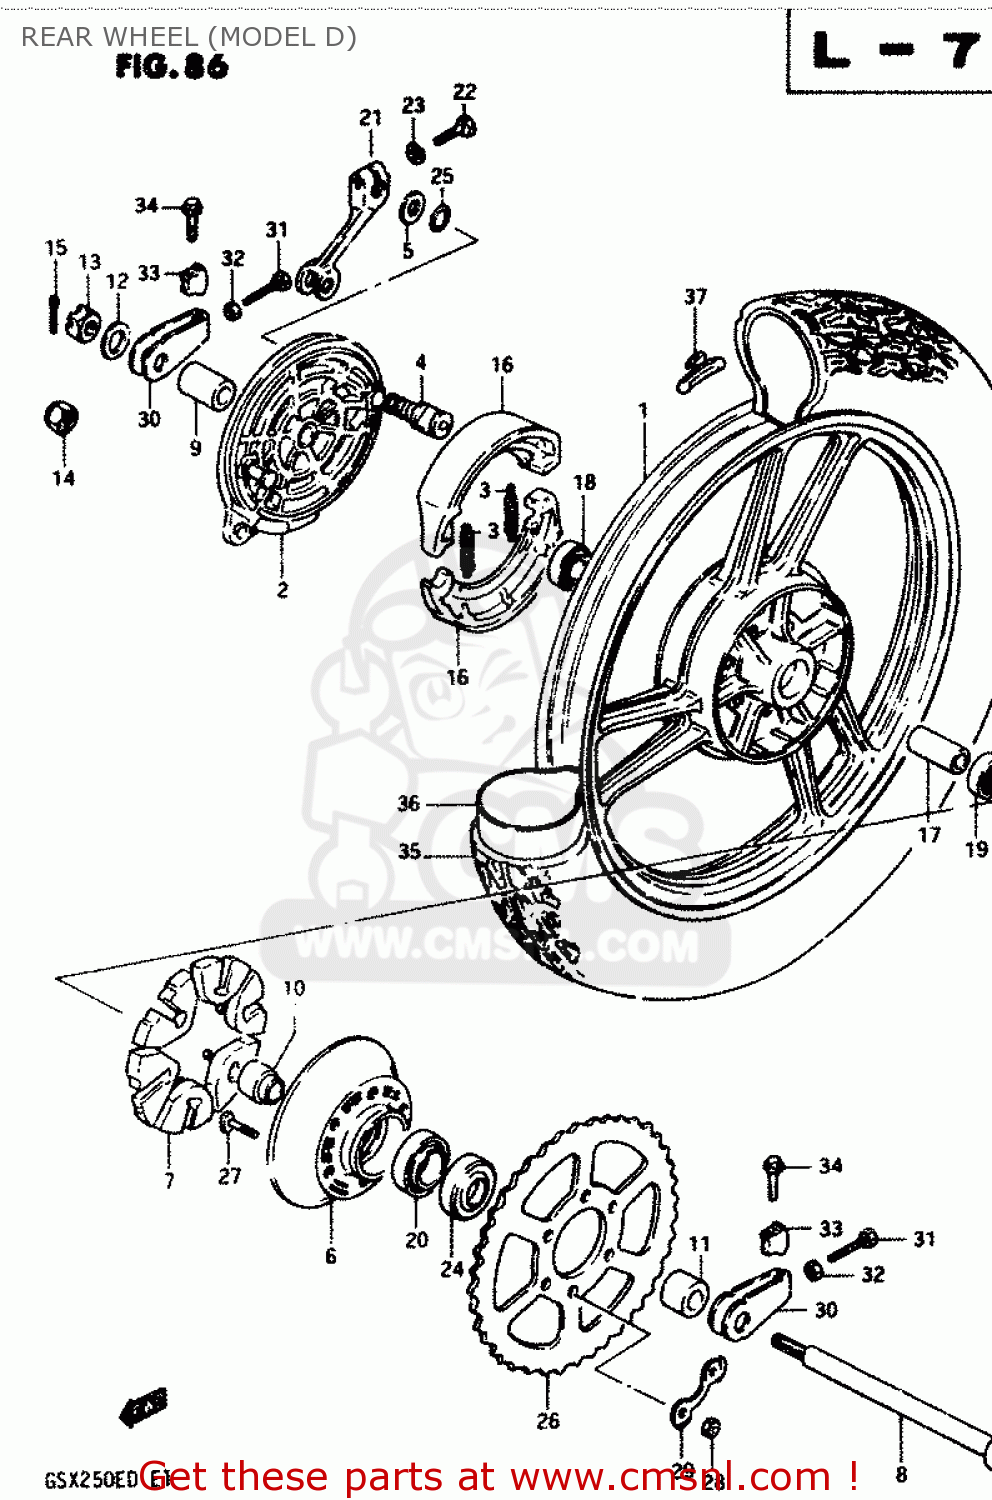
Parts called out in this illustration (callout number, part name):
1	WHEEL, REAR (18X1.85)
2	PANEL,REAR HUB
3	SPRING,BRAKE SHOE
4	CAM,FRONT BRAKE
5	WASHER (15X24X1.6)
6	DRUM,REAR SPROCKET MOUNT
7	ABSORBER,RR HUB SHOCK
8	AXLE,REAR
9	SPACER(17.5X28X44.8)
10	SPACER,REAR HUB BEARING
11	SPACER(17X30.5X22.3)
12	WASHER (17X30X3.2)
13	NUT
14	NUT
15	PIN,COTTER
16	SHOE,BRAKE
17	SPACER (17.6X24X57)
18	BEARING
19	BEARING
20	BEARING
21	LEVER,RR BRAKE CAM
22	BOLT
23	LOCK WASHER
24	SEAL,OIL(30.5X52X8)
25	O-RING,BOSS
26	SPROCKET,RR NT
27	BOLT
28	NUT
29	WASHER
30	ADJUSTER,CHAIN
31	BOLT 8X50
32	NUT
33	SUPPORTER,CHAIN ADJUST
34	BOLT
35	TIRE
36	TUBE ASSEMBLY,WHEEL,INNER
37	BALANCER,WHEEL
